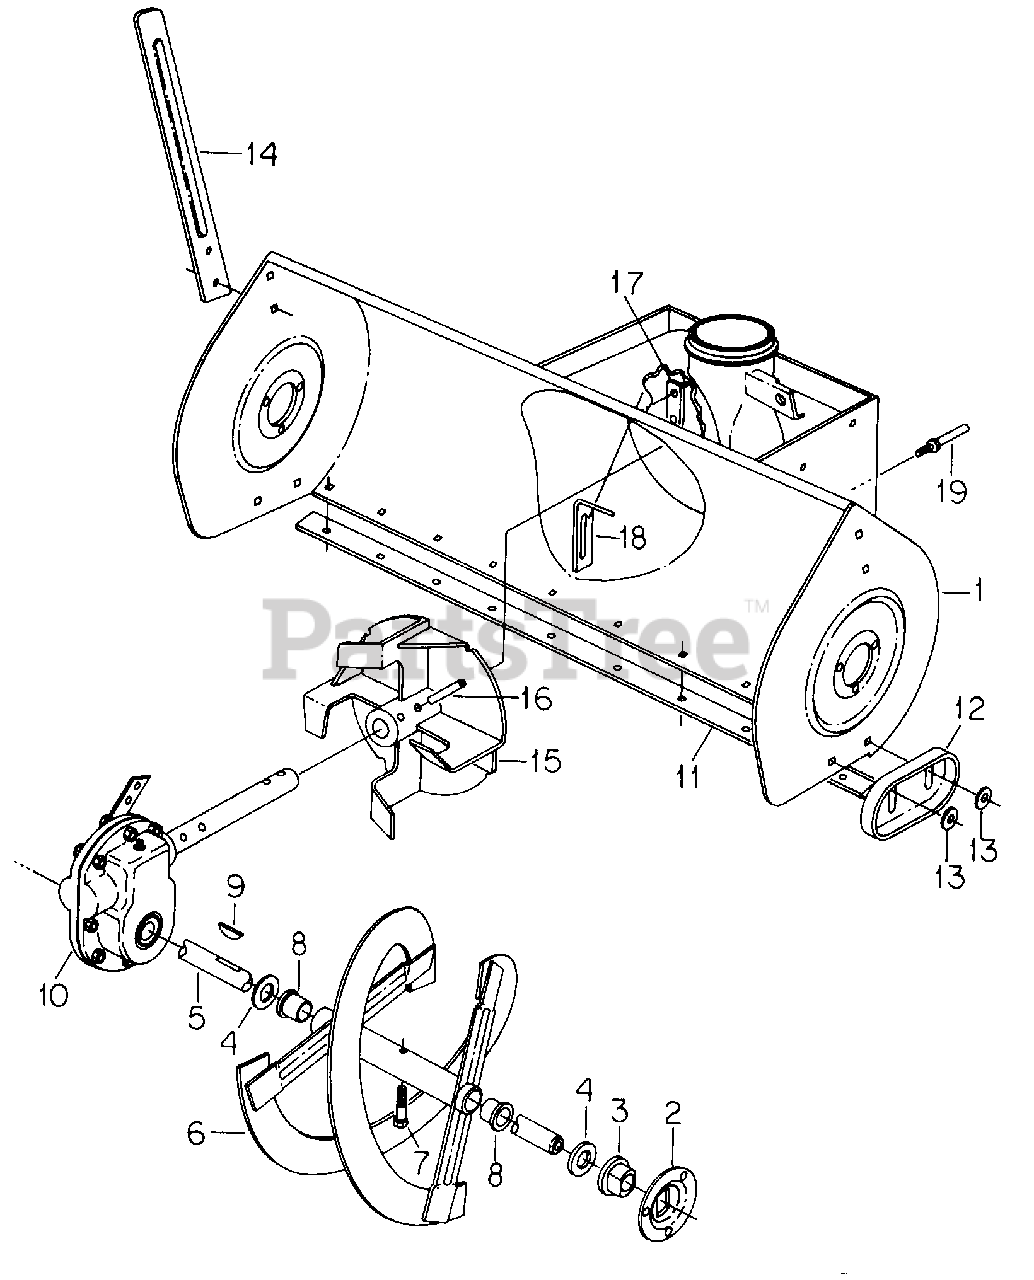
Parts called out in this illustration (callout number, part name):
1	Housing w/Product Graphic, Blower Product Graphic, Caution
2	Housing Bearing
3	Bearing, Auger Shaft
4	Washer, 1.031 X 1.750 X .105
5	Shaft, Auger
6	Auger, LH
7	Bolt, Shear
8	Bushing, Auger
9	Key, 1/4 X 3/4 SAE 91 Woodruff
10	Gear Box Assy, Blower
11	Plate, Shave
12	Shoe, Skid
13	Washer, .40 X .88 X .60 Belleville
14	Guide, Blade
15	Fan, Blower
16	Pin, 5/16 X 1-3/4 Hvy Pln Cld Spr
17	Support, Gear Housing Rear
18	Support, Gear Housing Center
19	Stud, Locating
